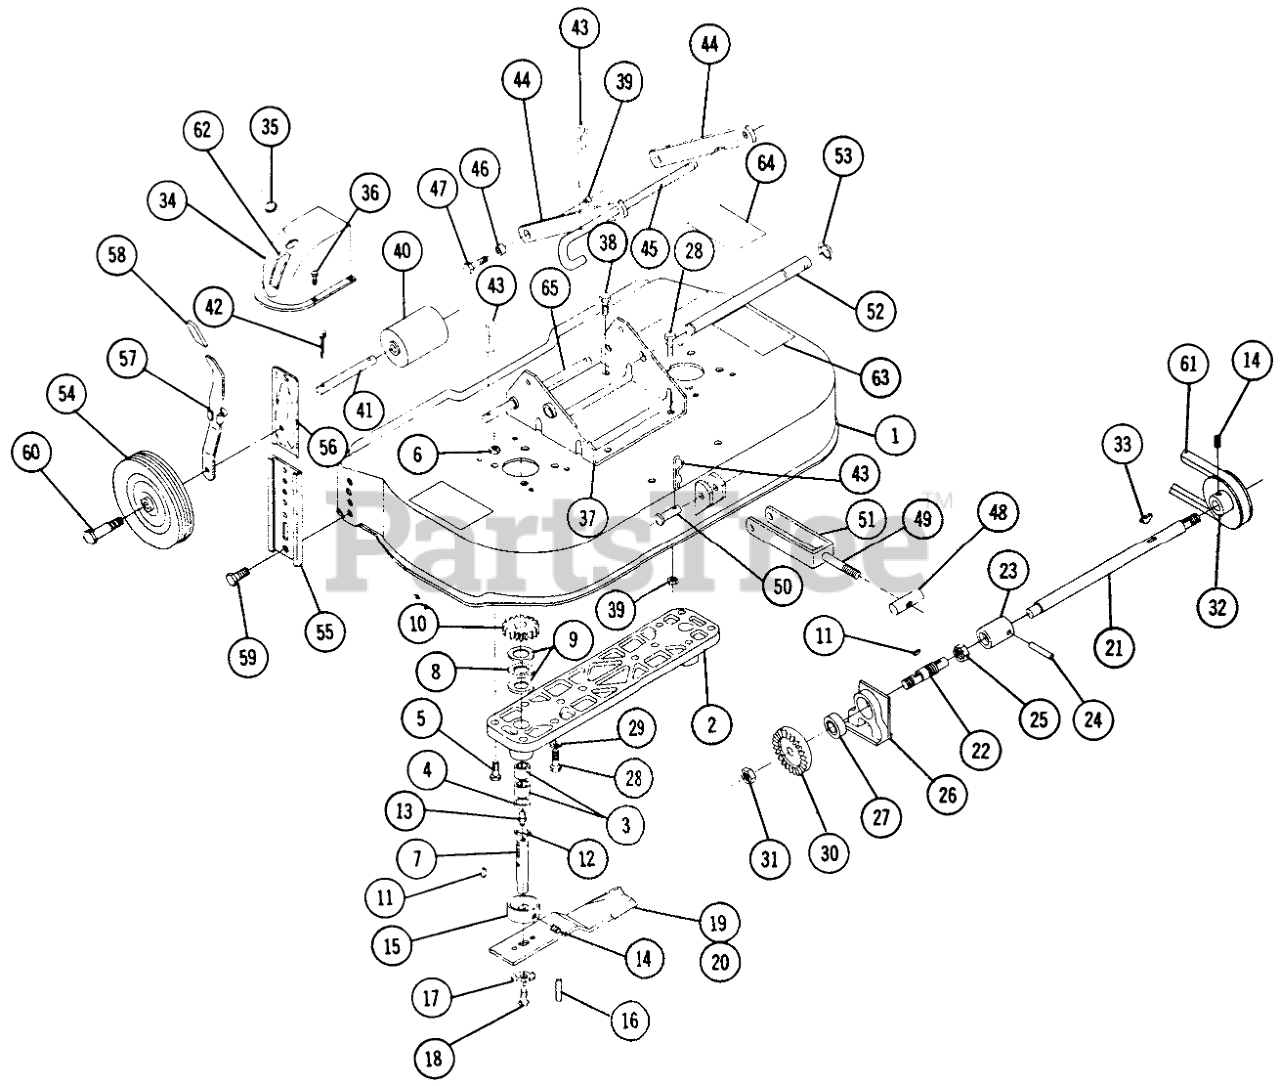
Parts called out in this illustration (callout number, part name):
1	Ass-y. Deck
5	Bolt 5/16-18 x 1
6	Nut-Nylok
7	SPINDLE SHAFT
14	Set Screw
16	SPIROL ROLL PIN
18	Bolt 3/8-16 x 7/8
23	Coupling
25	Nut Hex Jam 3/4-20
28	Bolt 3/8-16 x 1
29	Lockwasher
35	PLUG BUTTON
36	SCREW
37	Hanger
38	Bolt 3/8-16 x 3/4
39	3/8-16 E.S.
42	Cotter Pin
43	Hairpin
47	Bolt 3/8-16 x 7/8
49	Bolt Square Head 1/2-13 x 2 3/4
50	Clevis Pin
52	Shaft-Belt Tightener
53	E-RING
56	HT ADJ SLIDE
57	HT ADJ SPRING LEVER
60	BOLT SHOULDER
61	V BELT
62	Decal
64	Decal-Belt Diagram
65	Pin
